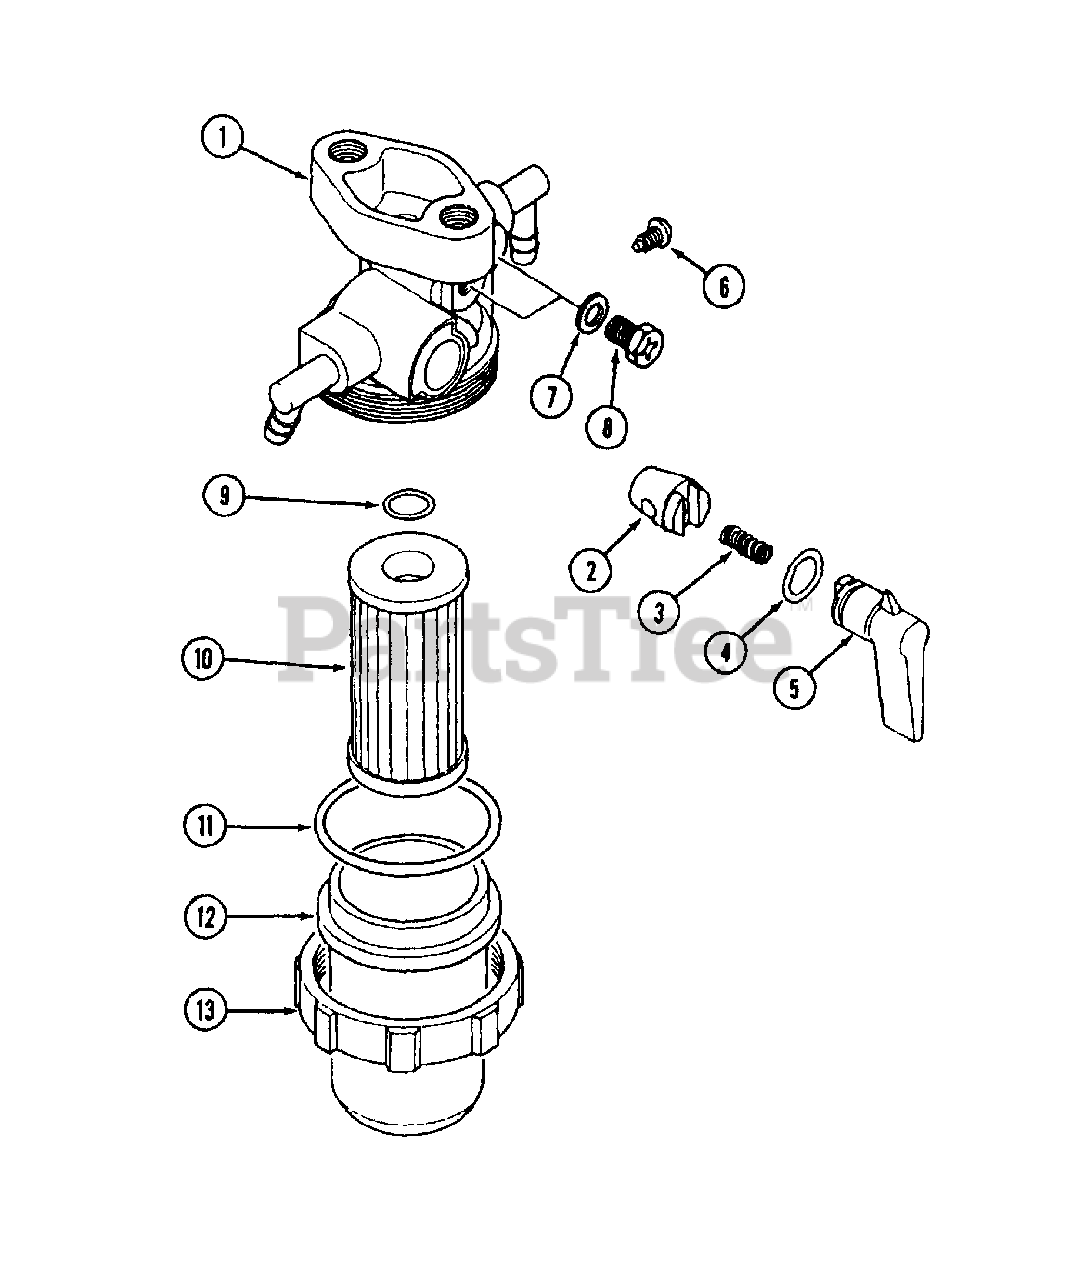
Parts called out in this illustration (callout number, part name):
1	Body Sub Ass'y., Fuel Filter
2	Valve
3	Spring, Valve
4	O-Ring, Valve
8	Screw, Air Vent
9	O-Ring, Element
10	Element
11	O-Ring, Filter Cup
12	Cup, Filter
